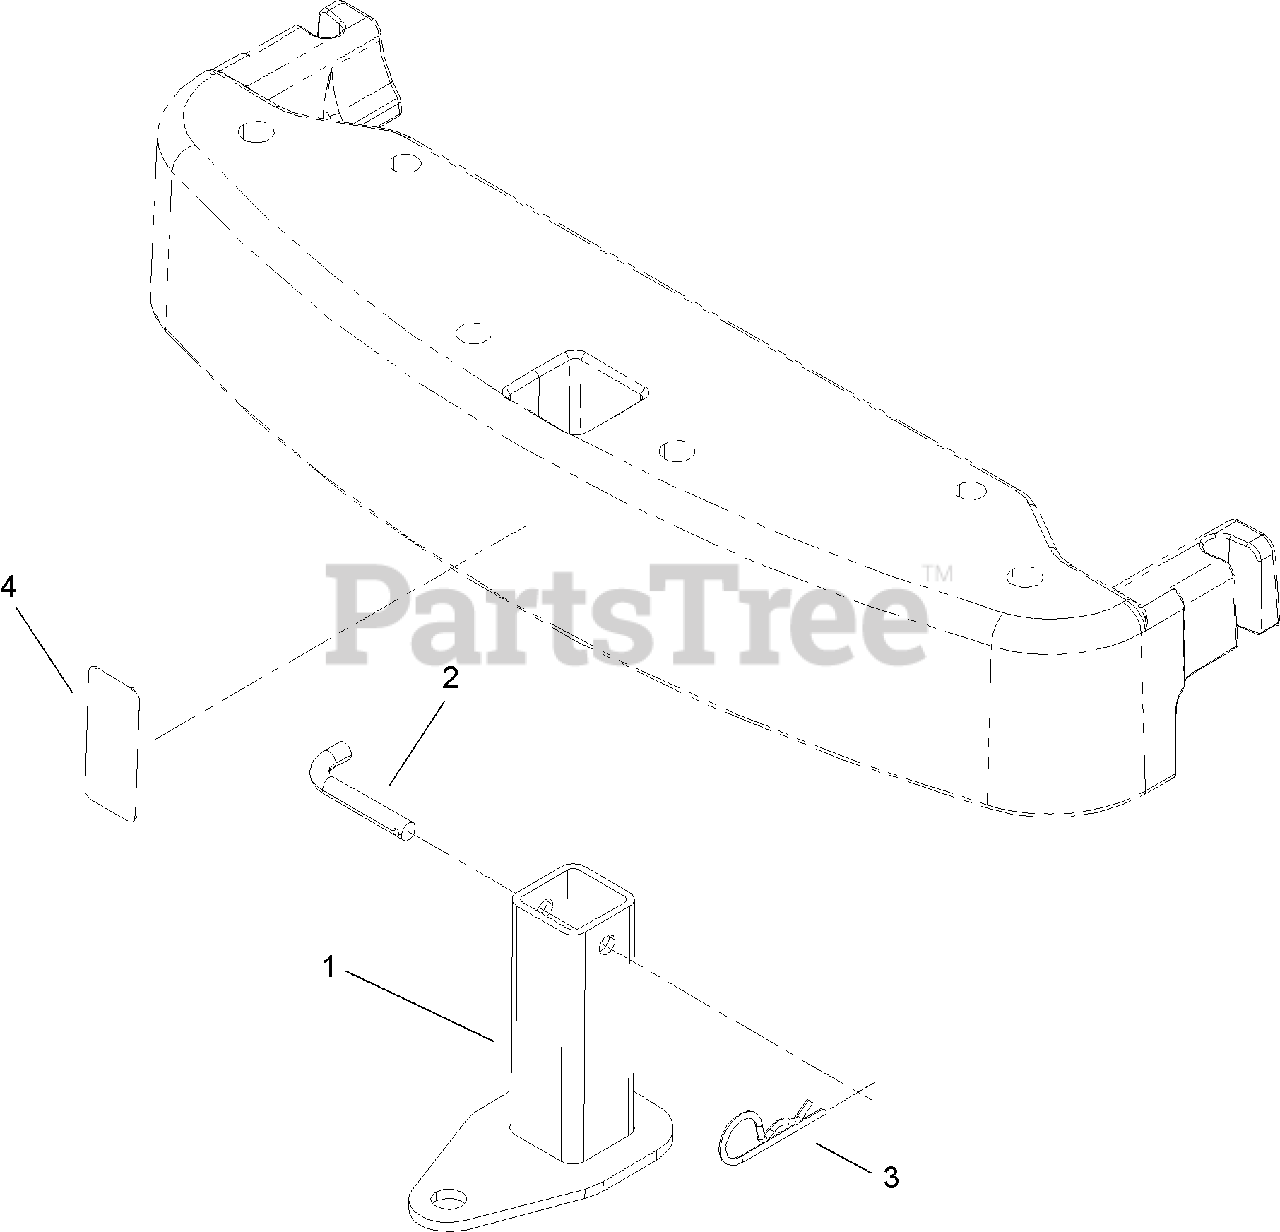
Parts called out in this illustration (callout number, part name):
2	PIN-HITCH
3	PIN-HAIR
4	DECAL-MAX DRAWBAR PULL
